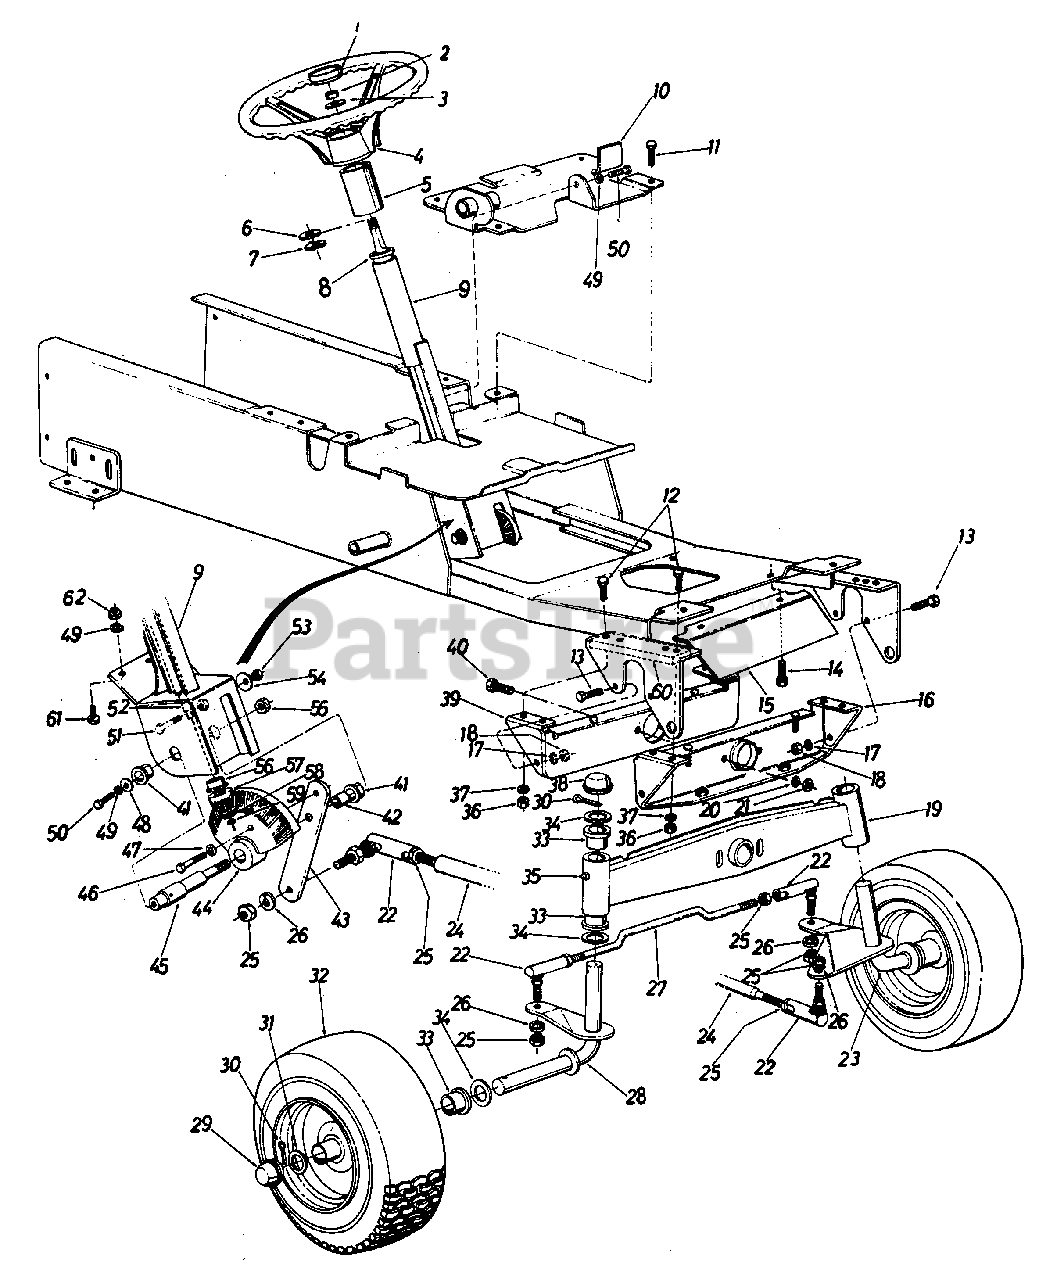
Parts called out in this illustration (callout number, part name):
1	Steering Wheel Cap
2	Hex Cent. L-Nut 5/16-18 Thd.
3	Bel l-Wash .
4	Steering Wheel
5	Steering Tube Outer
6	Double"D" Fl-Wash.
7	Wave Wash. .660 I.D. x .88 O.D.
8	Ball Brg. .63 I.D. x 1.38 O.D.
9	Steering Column Ass'y.
9	Steering Shaft
10	Dash Panel Base Plate Ass'y.
11	Hex Self Tap Scr. 3/8-16 x .75' Lg.
12	Hex Scr. 3/8-16 x 150" Lg.*
13	Hex Scr. 3/8-16 x 1.00" Lg.*
14	Hex Wash. S.F. Tap Scr. 3/8-16 x 1.25" Lg.
15	Dust Shield
18	Hex Nut 3/8-16 Thd.*
19	Pivot Bar Ass'y.
20	Bell-Wash. 3/8" Scr.*
21	Hex Cent. L-Nut 3/8-16 Thd.*
22	Drag Link End
23	Axle Ass'y. L.H.
24	Drag Link
25	Hex Nut 1/2-20 Thd.
26	L-Wash. 1/2" Scr.*
27	Tie Rod
28	Axle Ass'y. R.H.
29	Dust Cover
30	Cotter Pin 3/16" Dia. x 1.50" Lg.*
31	Fl-Wash. 1.00" I.D. x 1.62" O.D.
32	Front Wheel Tire Only
32	Air Valve
33	Flange Brg. 1.00" I.D.
34	Fl-Wash. 1.00" I.D. x 1.62" O.D.
35	Grease Fitting
36	Hex Nut 3/8-16 Thd.*
37	L-Wash 3/8" Scr.*
38	Dust Cover
40	Hex Scr. 3/8-16 x 2.50" Lg.*
41	Flange Brg. w/ Flats .753 I.D.
42	Steering Gear Shaft Spacer
43	Steering Arm
44	Bevel Gear
45	Steering Gear Shaft
46	Hex Scr. 3/8-16 x 1.50" Lg.*
47	L-Wash. 3/8" Scr.*
48	Fl-Wash. .406 I.D. x 1.25" O.D.
49	L-Wash. 3/8" Scr.*
50	Hex Scr. 3/8-16 x .75" Lg.*
51	Nylon Hex Scr. 3/8-16 x 1.25" Lg.
52	Steering Shaft
53	Hex Jam Nut 3/8-16 Thd.
54	Bell-Wash. .400 I.D. x 1.13 O.D.
55	Hex Ins. L-Nut 1/2-20 Thd.
56	Hex Flange Brg. .630 I.D.
57	Pinion Gear
58	Fl-Wash. 3/8" Dia.
59	Hex Cent. L-Nut 5/16-24 Thd.
62	Hex Nut 3/8-24 Thd.*
